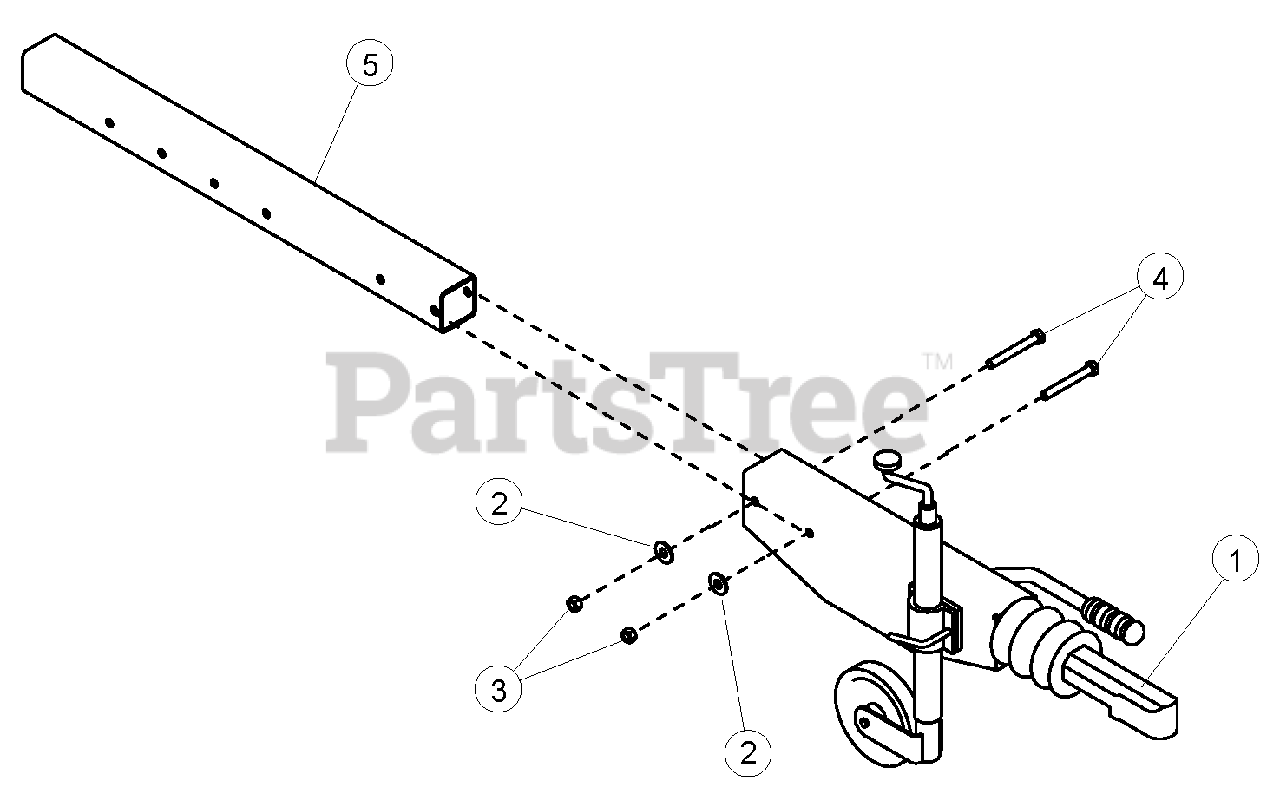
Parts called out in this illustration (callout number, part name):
1	COUPLING, SURGE WITH JOCKEY WHEEL
2	WASHER, 1/2" FLAT ZP
3	NUT, 1/2" CENTERLOCK GRB ZP
4	BOLT, 1/2 X 4 HEX CPS G5 ZP
5	TUBE, CHIPPER HITCH
